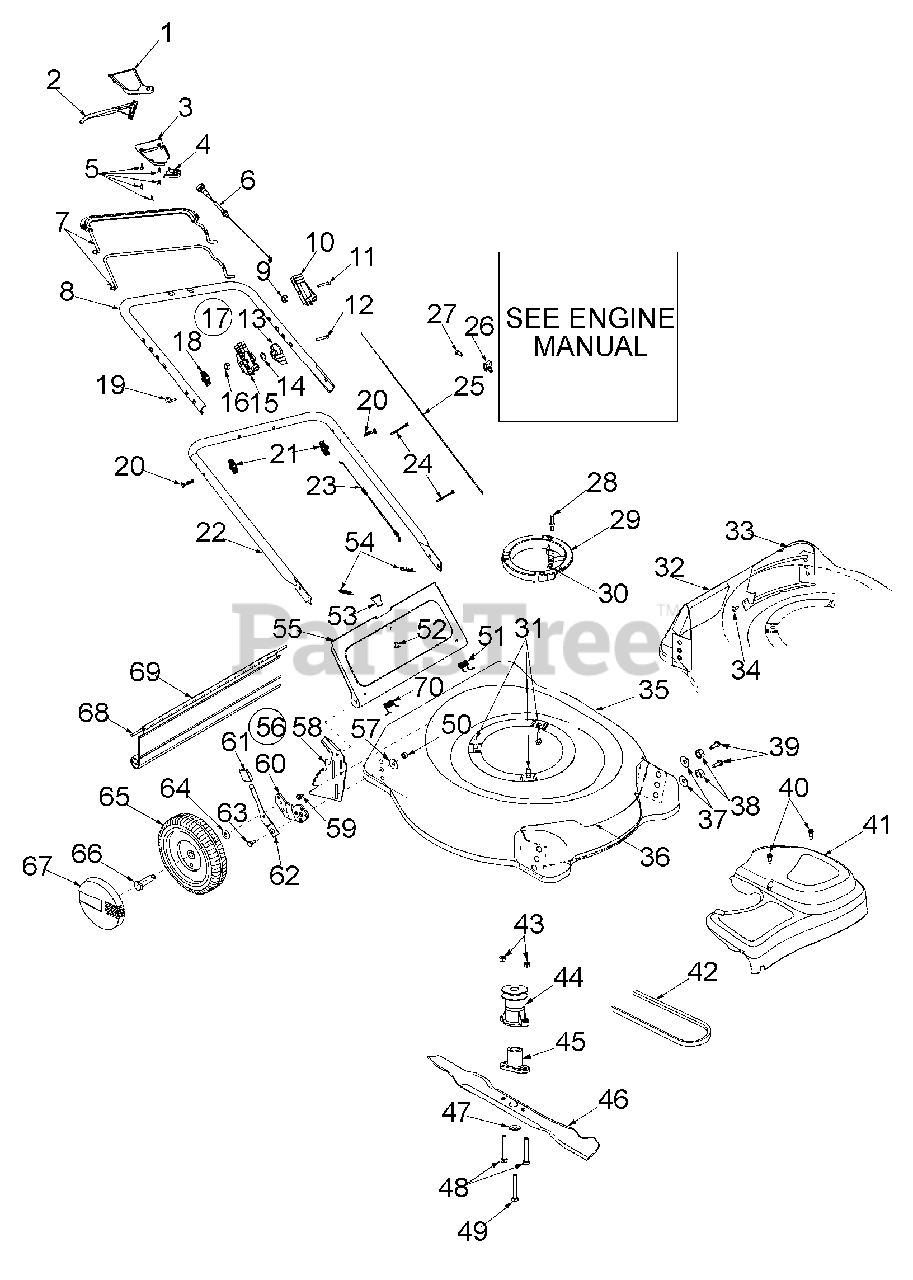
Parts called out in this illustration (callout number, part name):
1	Upper Drive Cover
2	Drive Lever
3	Lower Drive Cover
4	Mounting Cap
5	Screw #10-12: 75
6	Drive Cable
9	Hex Lock Nut 1/4-20
10	Throttle Hsg. w/o Lever
11	Scr. Oval C-Sunk 1/4-20 x 1.31
12	Scr. Oval C-Sunk 1/4-20 x 1.81 Scr. 1/4-20
13	Throttle Lever
14	Curved Washer .663 x .980 x .014
15	Throttle Housing
16	Hex Lock Nut 1/4-20 Thd.
17	Throttle Body Comp.
19	Eye Bolt 1/4-20
20	Carriage Bolt 5/16-18 x 2.0
21	Knob
23	Throttle Cable: 55" B&S
24	Tie Cable
25	Control Cable 39" B&S
26	Cable Clamp B&S
27	Hex Screw: T: #10-32 x .625 Lg. (B&S)
28	Pin-Belt Keeper
29	Engine Spacer
30	Hex Nut 1/4-20 Thread
31	Tapp Screw w/Hex Lock Wash
34	Scr. AB: 1/4-14 .625 Trust
38	Bell Washer .39 x 1.13 x .062
39	Hex Screw 3/8-16 x .75
40	Screw #12 x .457
41	Trans Cover - Black
42	V-Belt
43	Hex Lock Nut 1/4-20
44	Drive Pulley
45	Blade Adapter Kit
46	21" Mulching Blade w/star
47	Bell Washer .396 I.D. x 1.140 O.D. x .095
48	Hex Screw 1/4-20 x 1.50
49	Hex Screw 3/8-24 x 2.50
50	Hex Nut 3/8-16
51	Torsion Spring L.H.
52	Scr. Tr. Mach #10-24 x .380
54	Cotter Pin
58	Handle Brkt Ass'y - LH
59	Hex Screw w/wsh. 1/4-14 x .62
60	Pivot Bar - LH
61	Knob
62	Spring Lever
63	Shldr Screw .500 Dia x .434 Long
64	Bell Washer .380 x .880 x .062
65	Wheel 8 x 1.75 Disk Bar Grey
66	Shldr Screw .498 x 1.445
67	Hubcap: Euro Grey
68	Wire
69	Rear Flap
70	Torsion Spring R.H.
